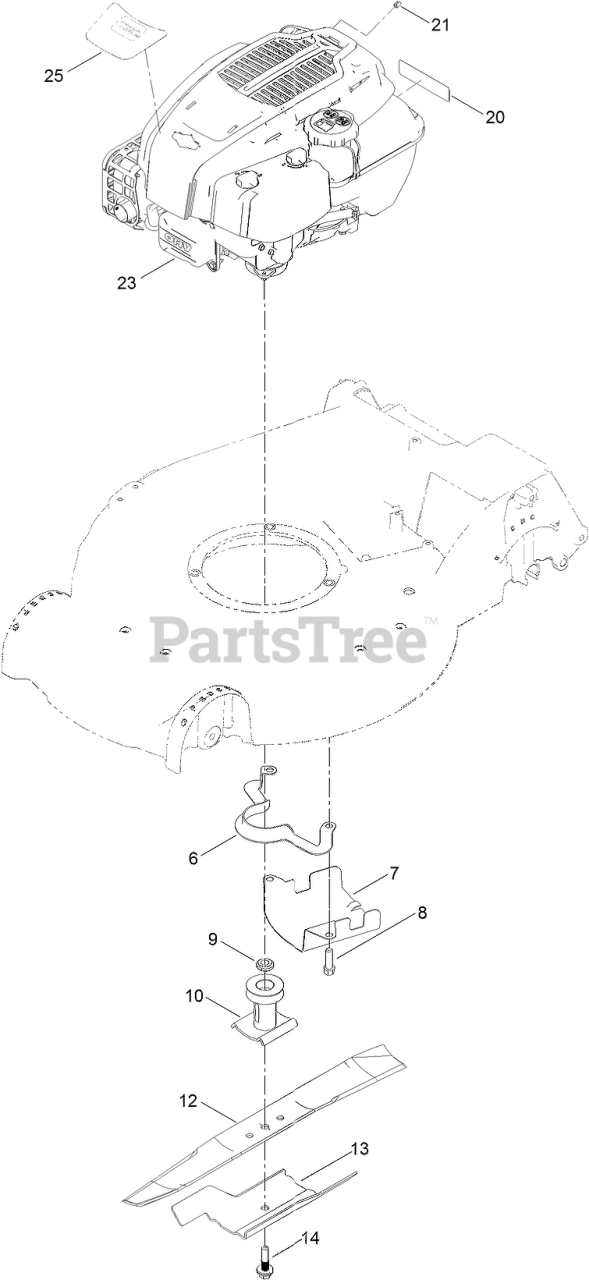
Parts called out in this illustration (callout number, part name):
6	GUIDE-BELT
7	SHIELD-GRASS
8	SCREW-TAPTITE
9	SPACER-DRIVER
10	DRIVER-BLADE
12	BLADE-21IN, RECYCLING
13	ACCELERATOR-BLADE
14	BOLT-BLADE
20	DECAL-ARRESTOR, SPARK
21	STOP-ROPE
23	ENGINE-BRIGGS 875 ES SS
25	DECAL-ENGINE
